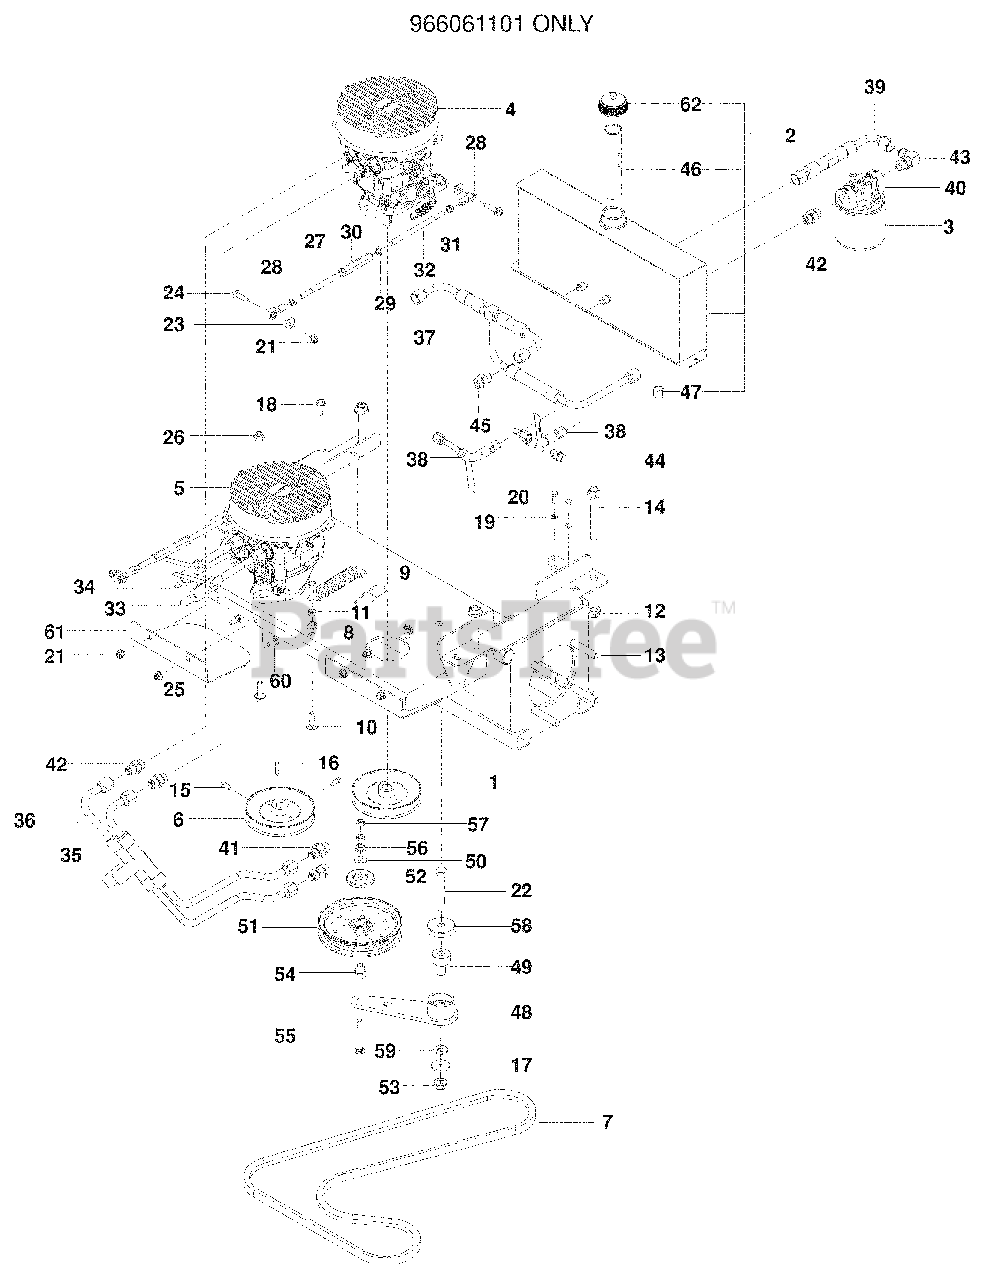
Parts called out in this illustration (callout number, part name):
1	FRAME, SUB
2	OIL TANK ASSY
3	FILTER, 25 MICRON
4	PUMP, 12CC RT
5	PUMP, 12CC LT
6	PULLEY, PUMP, 15MM
8	NUT 3/8-16 HEX WHIZLK
9	SPRING, PUMP
10	BOLT 3/8-16 x 1¼ RD HD
11	NUT 3/8-16 HEX JAM NYLOC
12	NUT ½-13 HEX FLG NYLOC
13	BOLT ½-13 x 2¾ HEX NYLOC
14	BOLT ½-13 x 4 HEX FLG
15	SCREW 5/16-18 x 5/8 SET
16	KEY, METRIC
17	WASHER ½ FLAT
18	BOLT 5/16-18 x 1 THD FRM
19	WASHER ¼ SPLIT LOCK
20	BOLT ¼-20 x ¾ HEX NYLOC
21	NUT 5/16-18 HEX FLG NYLOC
22	BOLT ½-13 x 3¼ HEX NYLOC
23	WASHER 5/16 STD FLT
24	SCREW 5/16-18 x 1¼ TPBLT
25	SCREW 3/8-16 x 1¼ HEX FLG
26	NUT 3/8-16 HEX FLG NYLOC
27	LINKAGE, CONTROL, FT
28	BALL END, RT
29	NUT 3/8-24 HEX JAM
30	TURNBUCKLE 3/8
31	NUT 5/16-24 HEX
32	LINKAGE, CONTROL, RR
33	LINE, HYDRAULIC, RT-A
34	LINE, HYDRAULIC, RT-B
35	LINE, HYDRAULIC, LT-A
36	LINE, HYDRAULIC, LT-B
37	LINE, HYDRAULIC, CHARGE
38	LINE, HYDRAULIC, CASE
39	LINE, HYDRAULIC, SUCTION
40	FILTER HEAD
41	STRAIGHT CONNECTOR
42	STRAIGHT CONNECTOR
43	ELBOW 90O ADJ
45	STRAIGHT CONNECTOR
46	TUBE, ANTI-SPLASH
48	ARM, IDLER, w/ BEARINGS
49	PIVOT, BEARING
50	WASHER 3/8 THICK
51	IDLER PULLEY
52	SHIELD, DUST
53	NUT ½-13 HEX FLG NYLOC
54	PIVOT, IDLER
55	BOLT 3/8-16 x 2¾ RD HD
56	NUT 3/8-16 HEX WHIZLK
57	NUT 3/8-16 HEX JAM NYLOC
58	SHIELD, DUST
59	WASHER ½" BELLEVILLE
60	BOLT 5/16-18 x ¾ RD HD
61	SHIELD, PULLEY
62	CAP, HYDRAULIC
